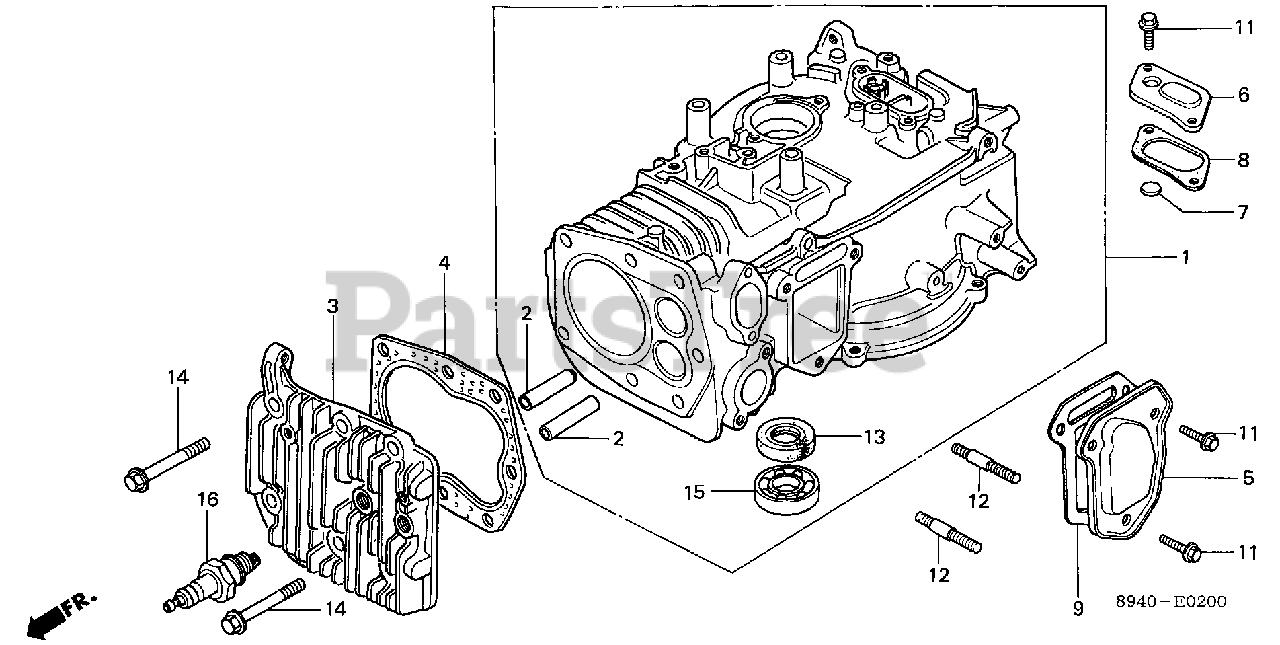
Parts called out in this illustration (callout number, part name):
1	CYLINDER ASSY.
2	GUIDE, VALVE (OS)
3	CYLINDER HEAD
4	GASKET, CYLINDER HEAD
5	COVER, TAPPET
6	CAP, BREATHER CHAMBER
7	VALVE, BREATHER
8	GASKET, BREATHER CAP
9	GASKET, TAPPET COVER
11	BOLT, FLANGE (6X12) (CT200)
13	OIL SEAL (25X41X6)
14	BOLT, FLANGE (8X45)
14	BOLT, FLANGE (8X45) (DENSO)
15	BEARING, RADIAL BALL (6205)
16	SPARK PLUG (BPMR6A-10) (NGK)
16	SPARK PLUG (W20MPR-U10)
